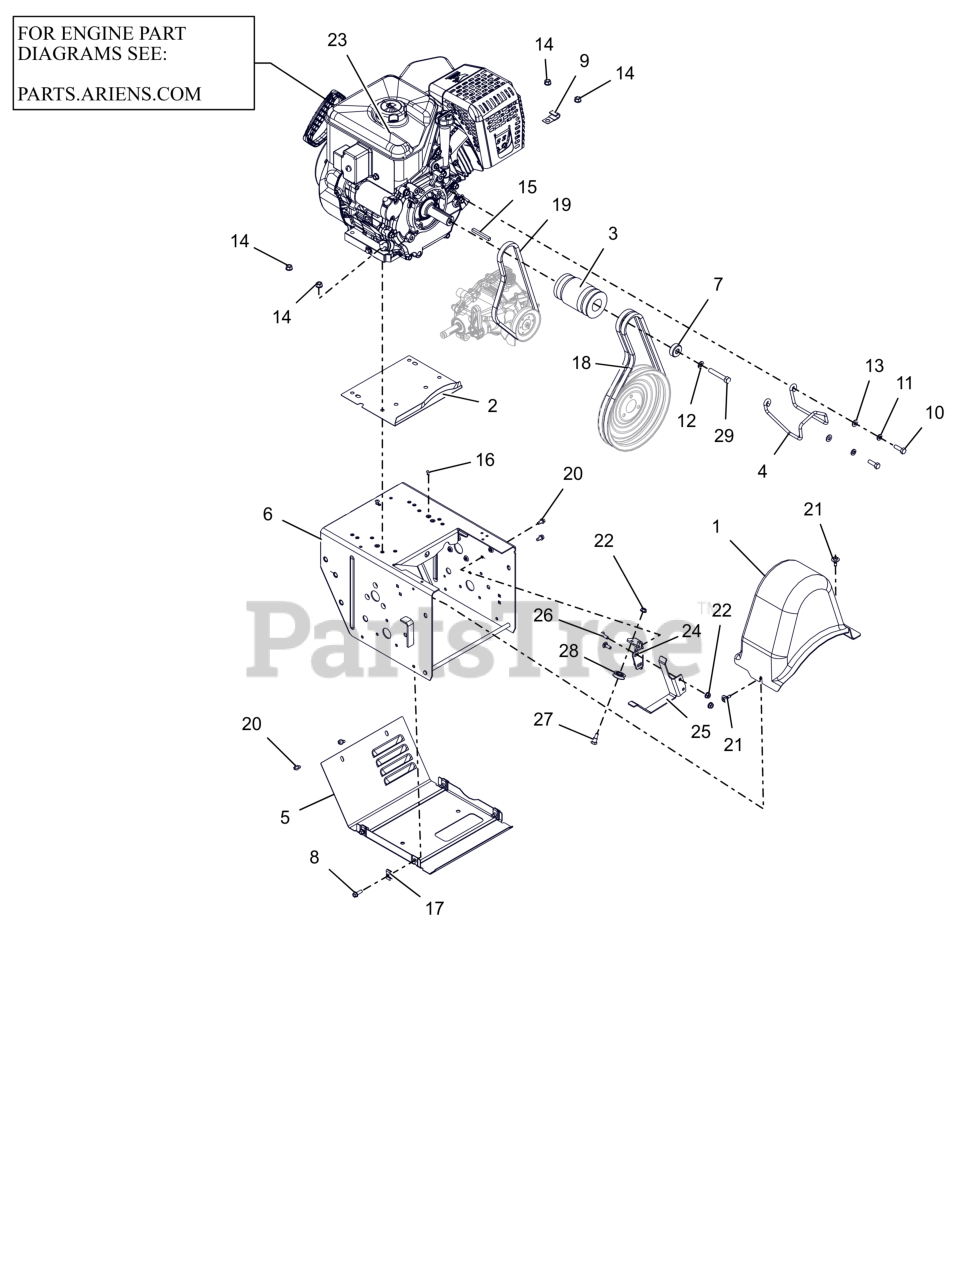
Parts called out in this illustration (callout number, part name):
1	COVER, BELT-LARGE
2	BAFFLE, WATER - LARGE BLOCK
3	SHEAVE, COMBO HYDRO WHEEL 4L
4	FINGER, BELT
5	COVER, BOTTOM - VENTILATED
6	FRAME, MAIN - PRO (WELDMENT)
7	BSHG, SPCR .406 X 1.250 X .500
8	BLT, HWH .25-20X.75 G5 ZCC
9	J-CLAMP
10	BLT, HEX 0.3125-24X1 G5 ZCC
11	WSHR, LK-HVY .312X.097 ZCC
12	WSHR,LK-REG .375X.094 ZCC
13	WSHR,FLT .344X.688X.065 ZCC
14	NUT,LK-CTR-FLG .31-18 GF ZCC
15	KEY .25X.25X2.25
16	RVT, POP .1875 ZCC
17	NUT-RTNR .25-20X.56
18	V-BELT, HA-RAW EDGE (SET)
19	V-BELT, 4L-WRAPPED
20	SCR-TAP .25-20X.50 HWH ZCC
21	SCR-TAP .25-20X.5 CAPTIVE
22	NUT-LK-TOP-FLG .250-20 GF ZCC
23	ENGINE,EFI420 GEN3 120V/60W
24	BRACKET, CLUTCH CABLE
25	FINGER, BELT - FLAT
26	BLT, RHSN .25-20X.750 G5 ZCC
27	BOLT, SHLDR -.375 X .375 X .25-20
28	PULLEY, CABLE
29	BLT, HEX .38-24X2.25 G5 ZCC
